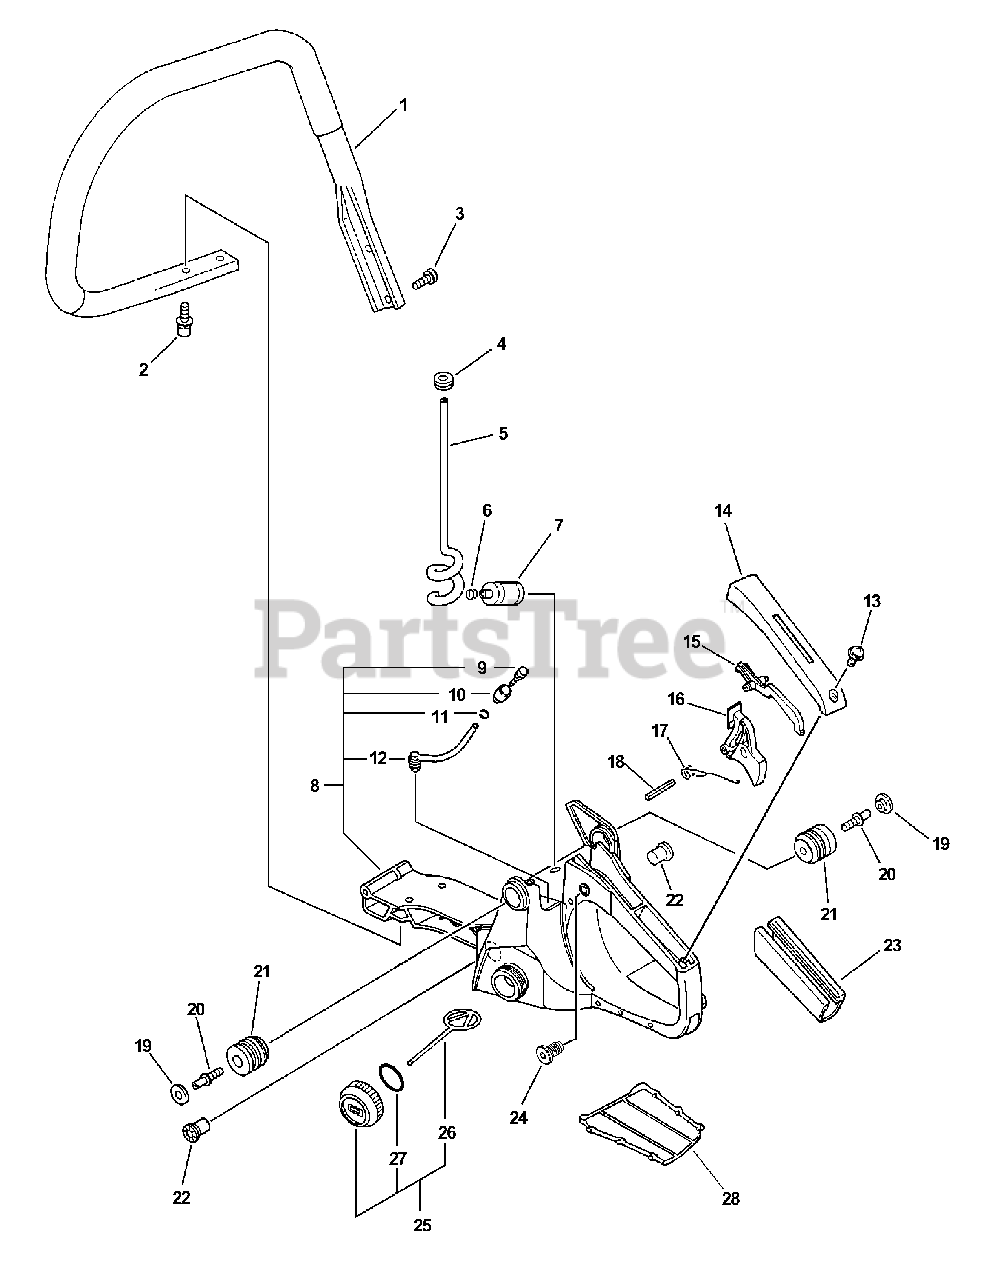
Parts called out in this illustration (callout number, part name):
1	HANDLE, FRONT
2	SCREW TAPPING 5×16
3	SCREW TAPPING 5×20
5	PIPE, FUEL 3×6×165
6	CLIP Ø6.5 MM
7	FILTER, FUEL
8	REAR HANDLE ASSY
9	VENT ASSY
10	HOLDER, VENT
11	CLIP Ø6.5 MM
12	PIPE, VENT - GROMMET
13	SCREW 4×14
14	COVER, HANDLE
15	LEVER, THROTTLE LOCKOUT
16	TRIGGER, THROTTLE
17	SPRING, THROTTLE RETURN
18	PIN, SPRING 4×30
19	CAP, CUSHION
21	CUSHION 5
22	CUSHION 5
23	GRIP, HANDLE
25	CAP ASSY, FUEL
26	CONNECTOR, CAP L= 60 MM
27	O-RING 22
28	SHIELD, SNOW
